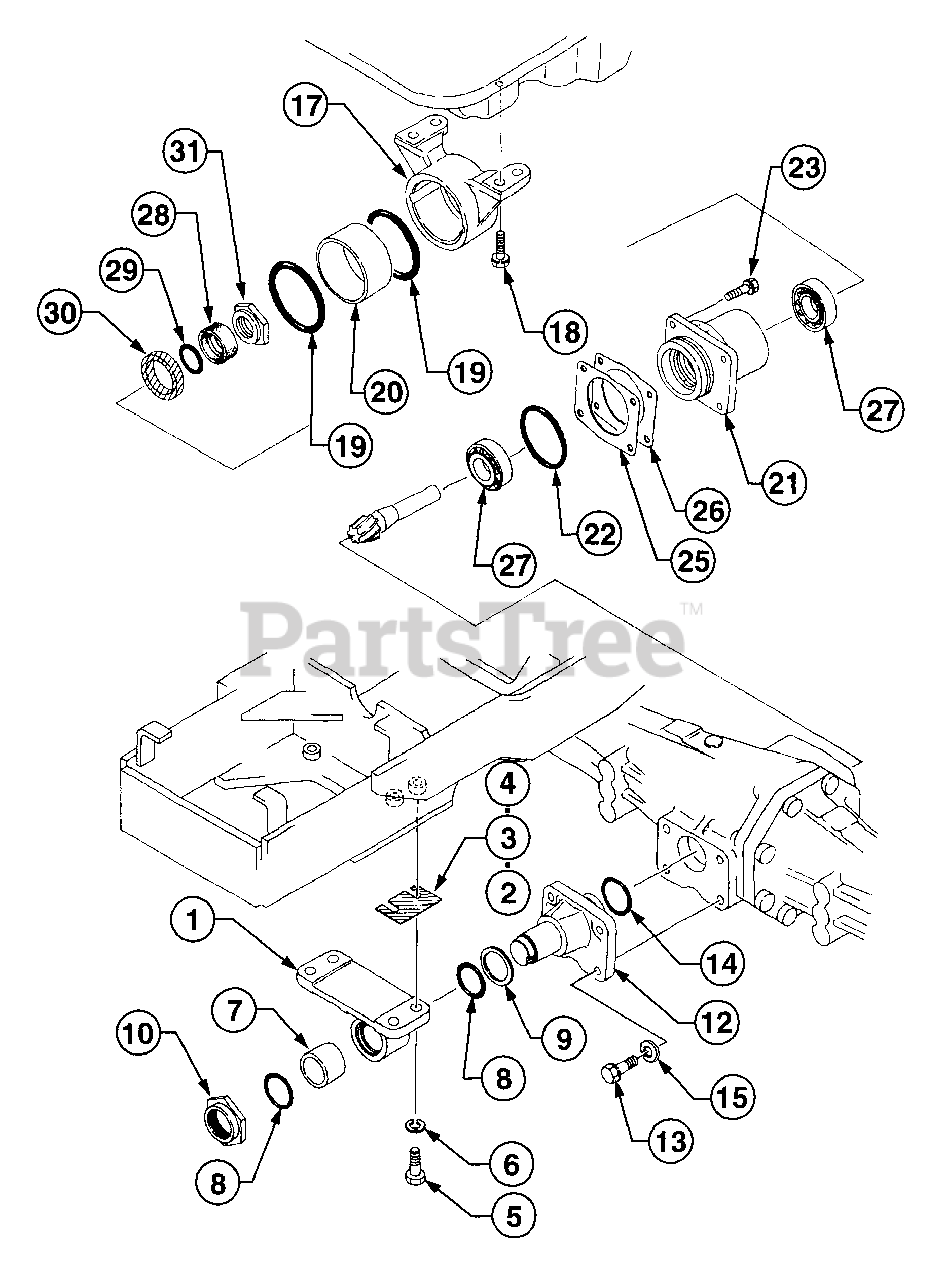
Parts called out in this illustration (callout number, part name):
1	Bracket, Front
13	Bolt, w/Washer
15	Washer, Spring
17	Bracket, Rear
21	Case, Bearing
27	Bearing, Taper
28	Bushing, Seal
